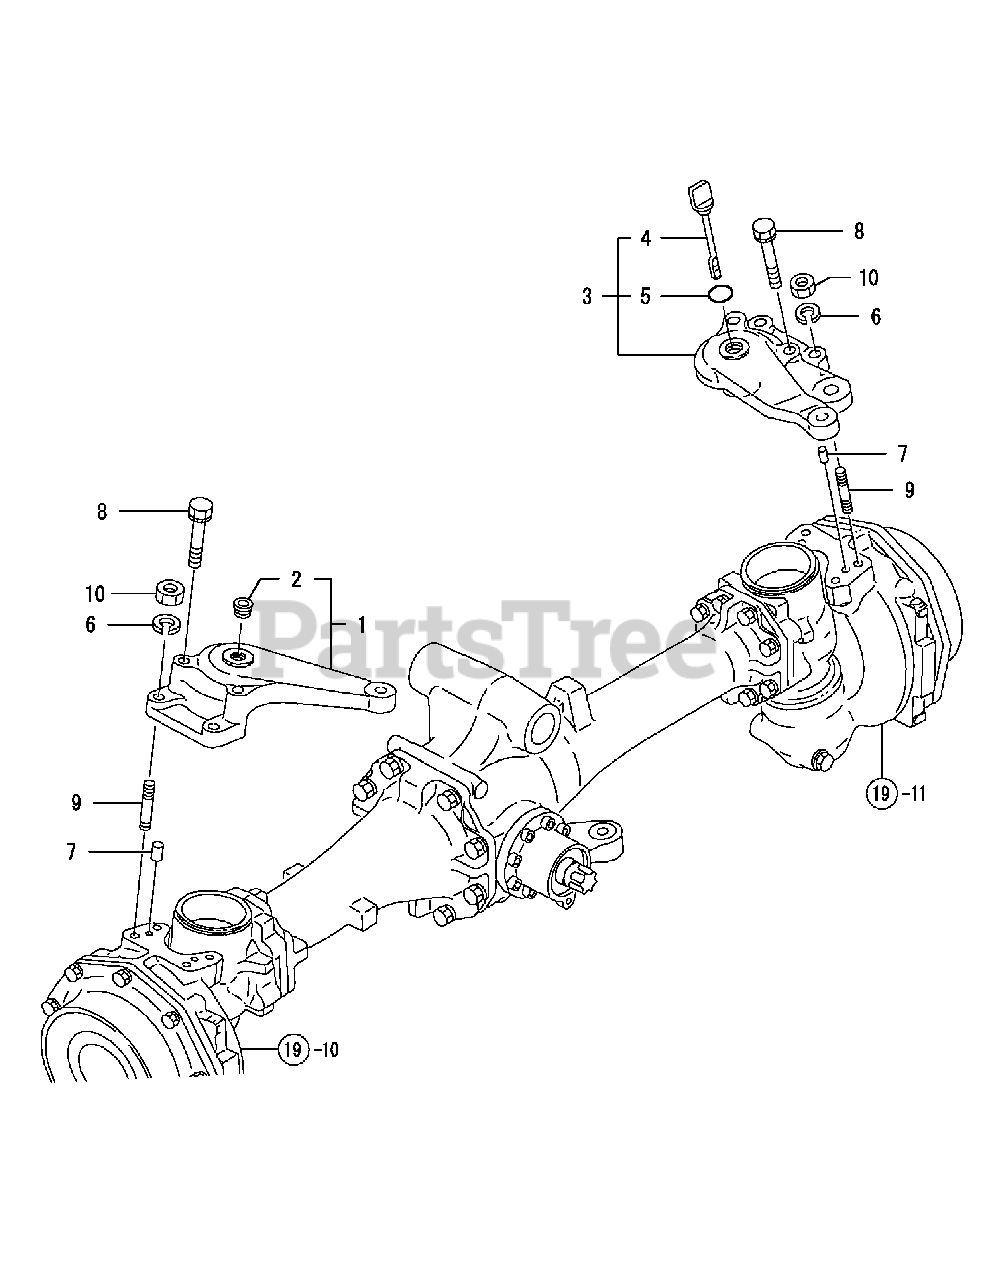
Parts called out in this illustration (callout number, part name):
1	ARM L COMP.,KNUCKLE
3	KNUCKLE ARM R CMP
4	GAUGE,OIL LEVEL
5	O-RING 1A P-18.0
6	SPRING WASHER 12
7	PARALLEL PIN 10X 18
8	BOLT W/WASHER12*80
9	STUD M12X 35 PLATED
